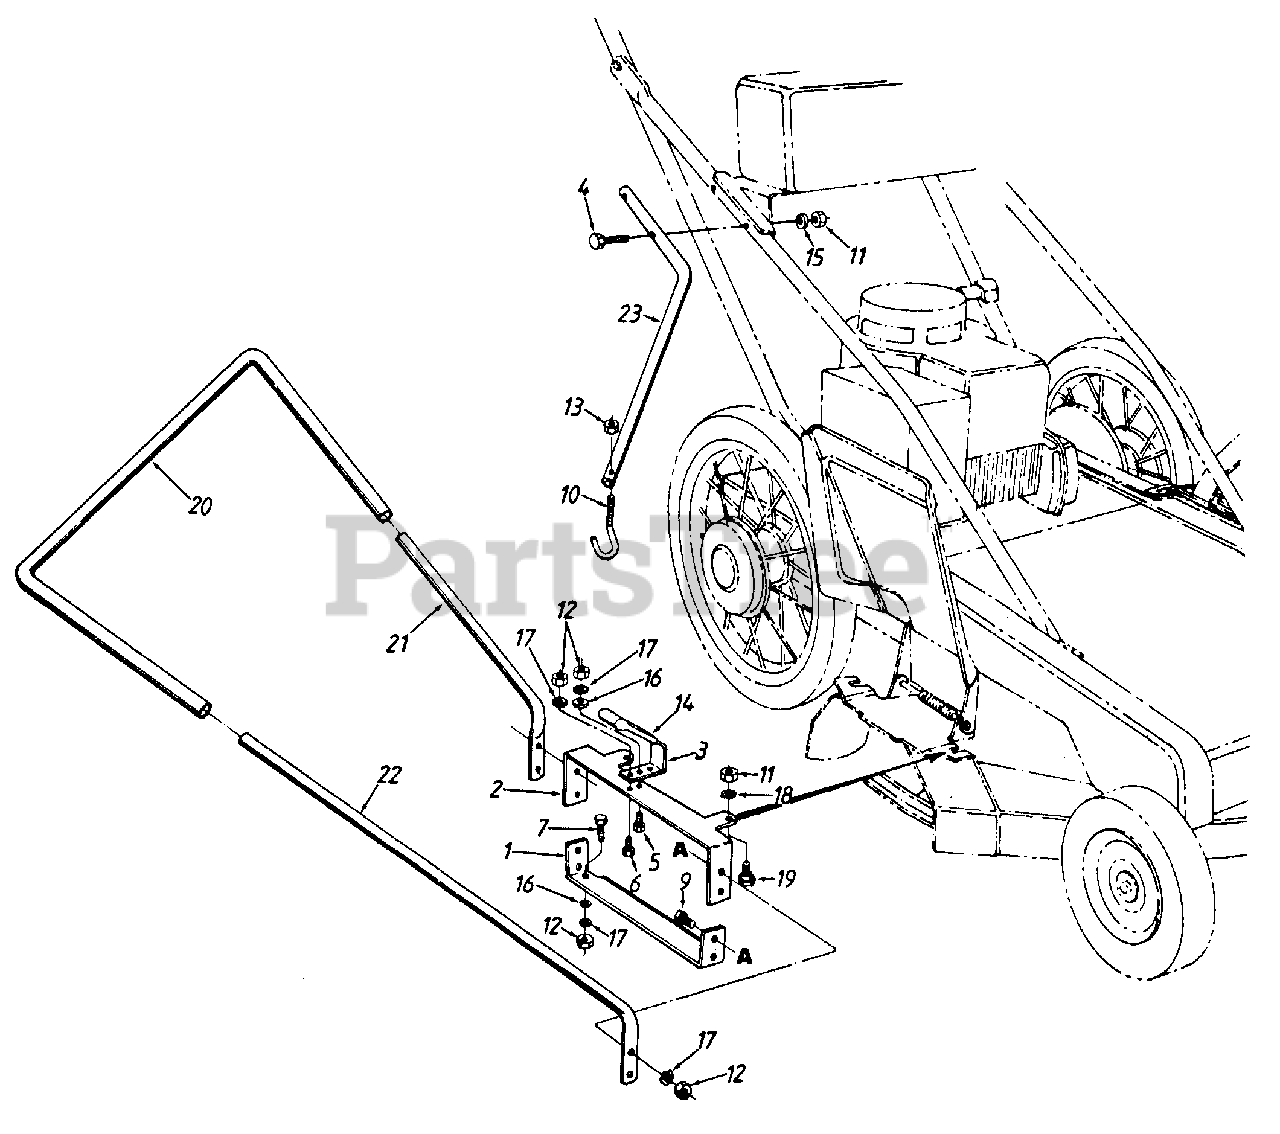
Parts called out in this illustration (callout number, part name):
1	Lower Opening Support
2	Upper Opening Support
4	Hex Bolt 5/16-18 x 2" Lg.
5	Hex Bolt 1/4-20 x .85" Lg.
6	Hex Bolt 1/4-20 x .62" Lg.
7	Hex Bolt 1/4-20 x .5" Lg.
9	Hex Bolt 1/4-20 x 1.25" Lg.
11	Hex Nut 5/16-18 Thd.
12	Hex Nut 1/4-20 Thd.
13	Hex Ins. Nut 1/4-20 Thd.
15	L-Wash. 5/16" I.D.
16	Fl-Wash. .281" I.D. x .5" O.D.
17	Ext. L-Wash. 1/4" I.D.
18	Ext. L-Wash. 5/16" I.D.
19	Shoulder Bolt
20	Upper Frame
21	Lower Frame
22	Lower Frame Arm
23	Holding Arm
